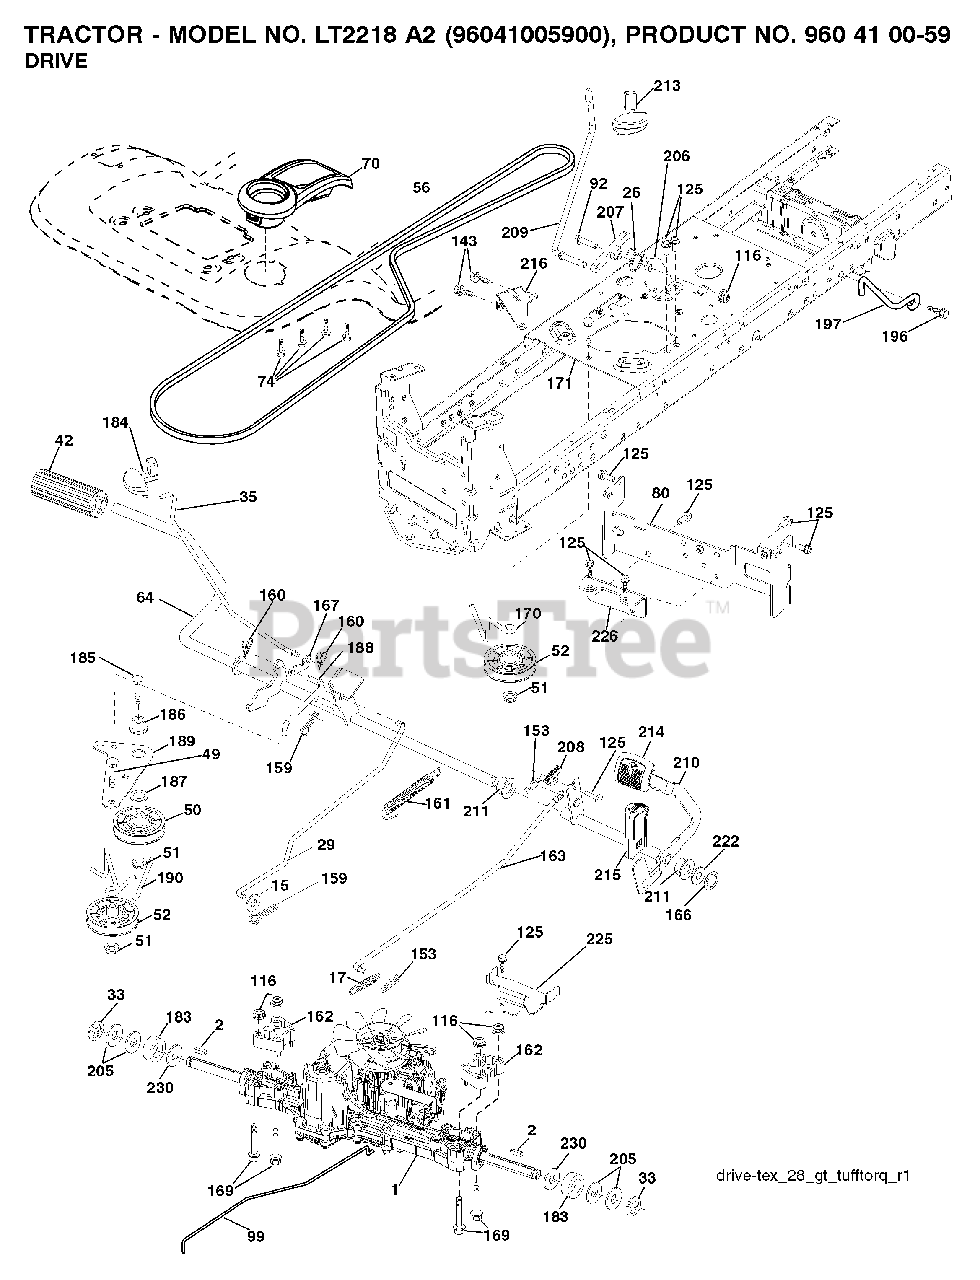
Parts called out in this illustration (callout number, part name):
2	SQUARE KEY
17	SPRING.BRAKE.K46.GREEN
26	SPRING.RETURN.CRUISE
29	ROD.BRAKE.K46
33	E-RING LT
35	ROD.BRKAE.PARKING.STEALTH
42	PEDAL COVER T
49	BOLT
50	IDLER.FLAT.910.OFFSET
51	NUT LOCK FLG 3/8-16 UNC
52	IDLER.V-GROOVE.910.OFFSET
64	SHAFT.ASM.PEDAL.BRK.CNTR
70	CONSOLE.TOOLBOX.PCH.ERGO.BLACK
74	SCREW.HI-LO.CONSOLE
80	STRAP TORQUE
92	BOLT
99	ROD ASM BYPASS
116	NUT LOCK HEX FLANGE 5/16-18
125	SCREW
143	SCREW LT
153	RETAINER M
159	COTTER PIN
160	RETAINER CLIP
161	SPRING.RETURN.CLUTCH.2006
162	SPACER.TRANSAXLE.18&22
163	ROD.CONTROL.PEDAL.K46
166	NUT.PUSH.625.2006
167	LATCH.BRAKE.SPRING
169	BOLT.HEX.FLNG.5/16-18X3.75
170	KEEPER.V-IDLER.CENTER.
171	BOLT
183	SPACER AXLE
184	HANDLE.PRKG.BRAKE.STLTH.TX.RED
185	BOLT
186	SPACER.RETAINER
187	WASHER 12/32X2X10GA
188	LINK.CLUTCH.GROUND.DRIVE
189	BELLCRANK.GROUND.DRIVE.TEX.
190	KEEPER.BELLCRANK.DRIVE
196	SCREW 3/8-16X1
197	LINK.CLUTCH.ANIT-ROTAT
206	BRKT.MOUNT.LATCH.CRUIS
207	LATCH.CONTROL.CRUISE
208	GEAR.SECTOR.CONTROL.CR
209	ROD.CONTROL.CRUISE.STEALTH.TEX
210	ROCKER.ASM.PEDAL.CONTR
211	BEARING.NYLON
213	KNOB.CONTROL.CRUISE
214	PEDAL.FORWARD.TEX.GT.4
215	PEDAL.REVERSE.TEX.GT.4
216	BRACKET.PULLEY.IDLER.W/TEX
222	WASHER 21/32 X 1-1/4 X 10 GA.
225	KEEPER.BELT.TRANSAXLE.K46
226	BRKT.MOUNT.TORQUE.K46.
230	WASHER.HARDENED
